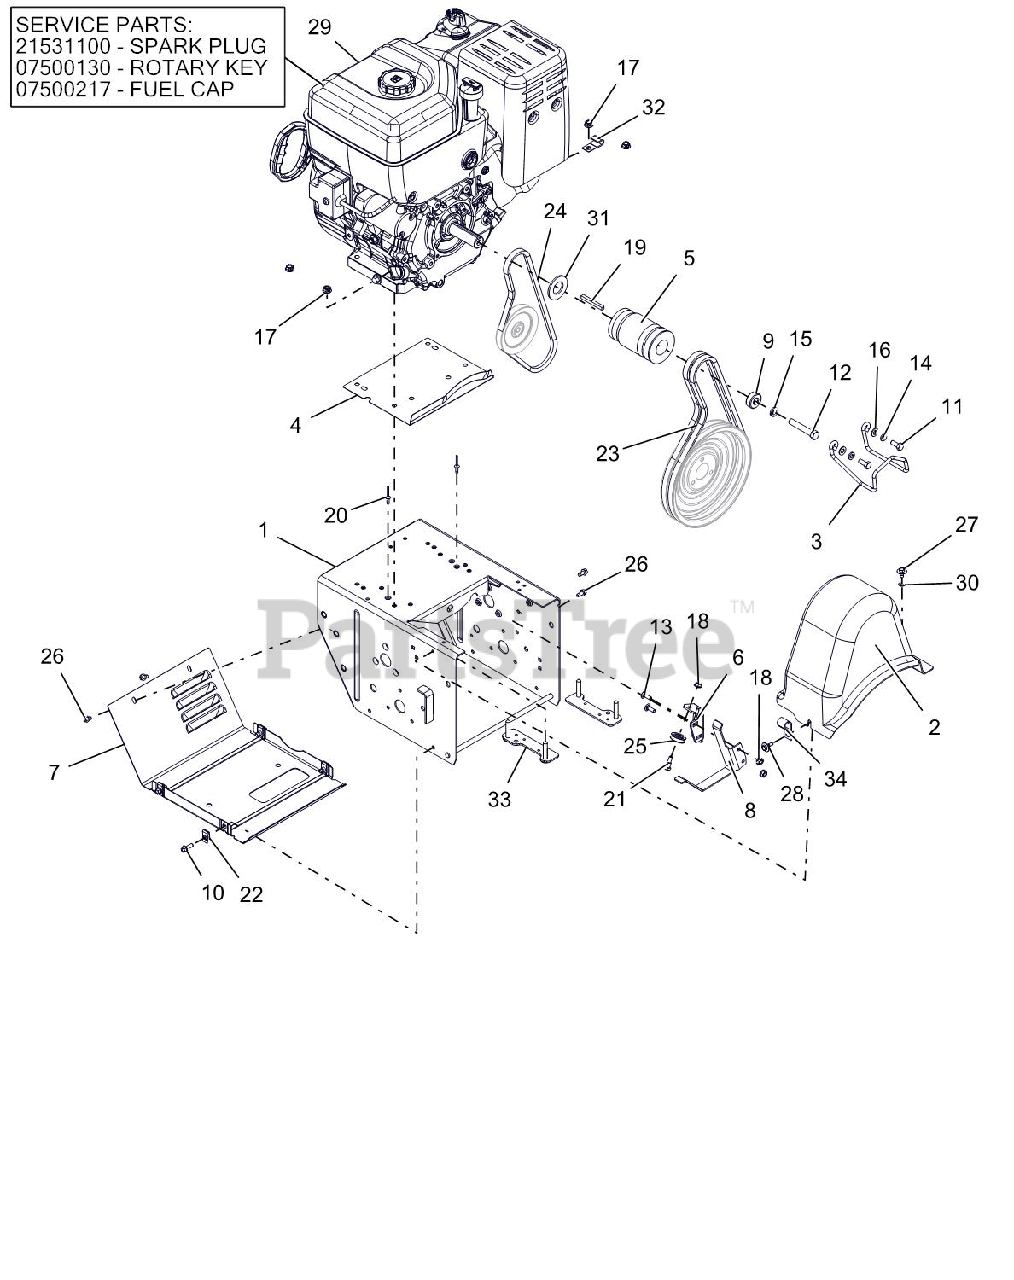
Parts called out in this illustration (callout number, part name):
1	FRAME, MAIN - PRO (WELDMENT)
2	COVER, BELT-LARGE
3	FINGER, BELT
4	BAFFLE, WATER - LARGE BLOCK
5	SHEAVE, COMBO HYDRO WHEEL 4L
6	BRACKET, CLUTCH CABLE
7	COVER, BOTTOM - VENTILATED
8	FINGER, BELT - FLAT
9	BSHG-SPACER .47X1.25X.50
10	BLT-HEX .25-20X.75 HWH YZ GR5
11	BLT-HEX .31-24X.75 YWZC GR5
12	BLT-HEX .44-20X2.50 GR5 YWZC
13	@BLT-RDHDSQNK .25-20X.75 G5YZ
14	WSHR-LK .312X.097 HVY YWZC
15	@WSHR-LK .44X.109 REG YWZC
16	@WSHR-FL-STL.344X.688X.065YWZC
17	@NUT-LK-CTR-FLG .31-18 YZ GR F
18	@NUT-LK-TOP-FLG .25-20 YWZC
19	KEY .25X.25X2.25
20	RVT-POP .187 YZ
21	BOLT, SHLDR-.375X.375X.25-20
22	NUT-RTNR .25-20X.56
23	V-BELT, HA-RAW EDGE (SET)
24	V-BELT, 4L-WRAPPED
25	PULLEY, CABLE
26	SCR-TAP .25-20X.50 HWH TR YWZ
27	SCR-TAP .25-20X.50 LGHWH TR YZ
28	SCR-TAP .25-20X.5 CAPTIVE
29	PLUG, SPARK 20HP B&S VANGUARD
29	CAP, FUEL - BRIGGS & STRATTON
29	ENGINE, BRIGGS PF 2100, 12V
29	KEY, IGNITION ROTARY B&S
30	NUT-PUSH .25X.50 O.D.
31	WSHR-FL-STL- 1.062X2.0X.134 YZ
32	J-CLAMP
33	STRAP, BOLT-LARGE
34	J-CLAMP
